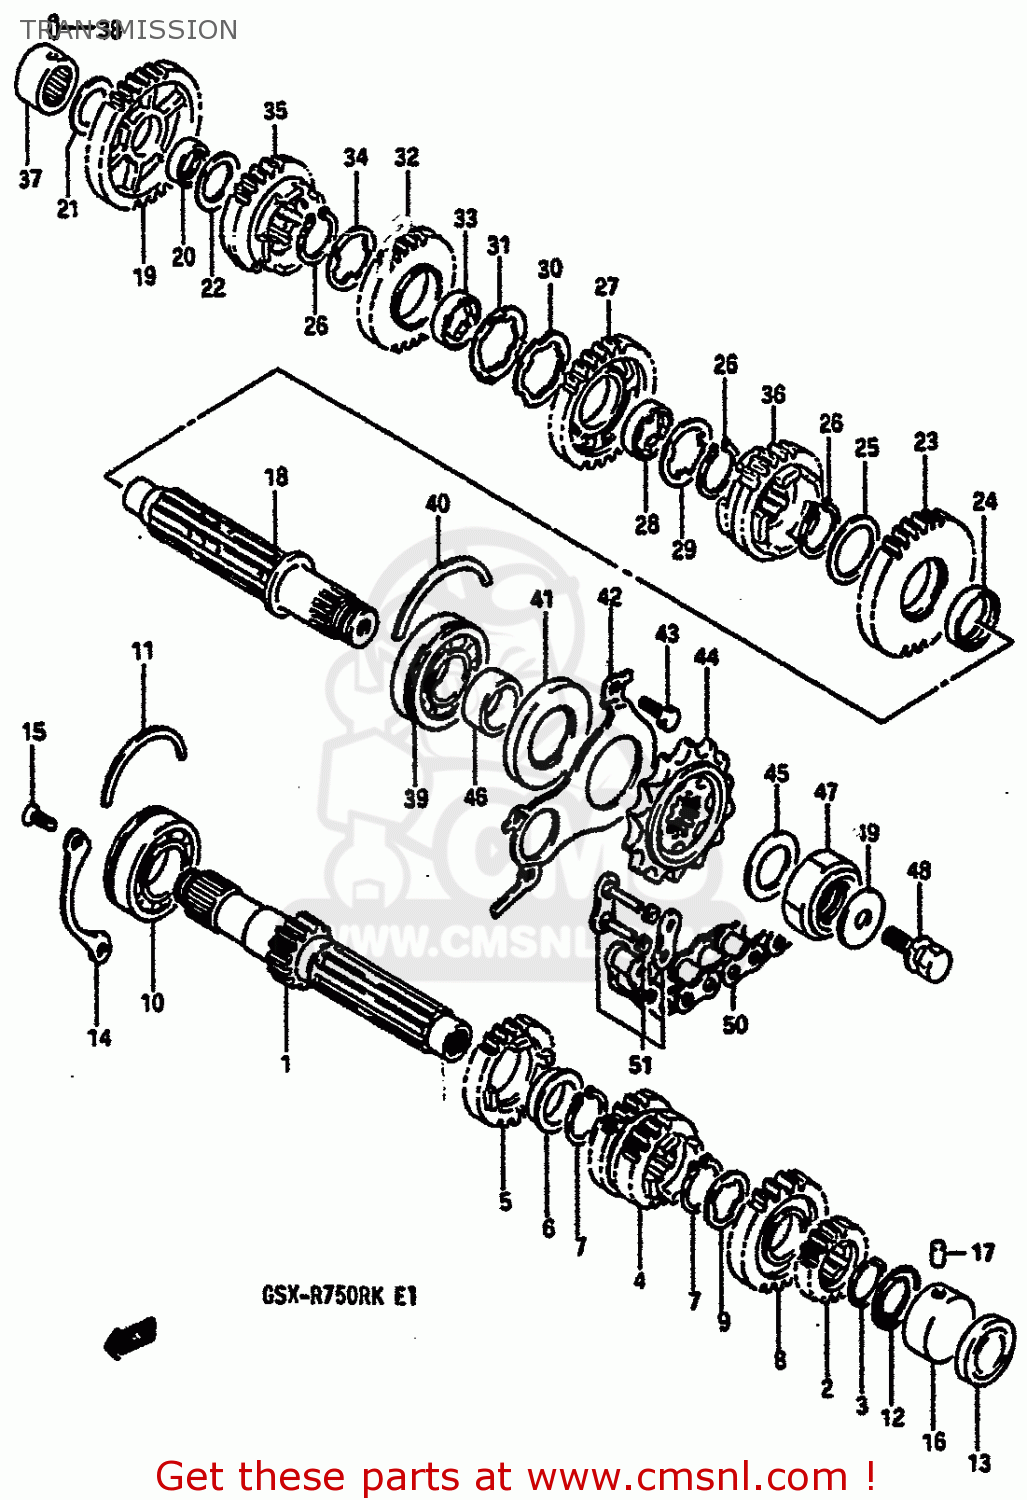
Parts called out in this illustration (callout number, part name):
1	COUNTERSHAFT (NT:13)
2	GEAR,2ND DRIVE (NT:17)
3	CIRCLIP
4	GEAR,3RD & 4TH DRIVE(NT:19/20)
5	GEAR,5TH DRIVE
6	BUSHING
7	RING,SNAP
8	GEAR,6TH DRIVE (NT:20)
9	WASHER,LOCK
10	BEARING(25X62X17)
11	C-RING
12	SEAL,OIL(20X31.2X2.7)
13	CAP,COUNTER SHAFT,L
14	RETAINER,CNTR SHAFT BEARING
15	SCREW
16	BEARING(20X34X17.5)
17	PIN
18	DRIVESHAFT
19	GEAR,1ST DRIVEN (NT:31)
20	BUSH(22X26X9)
21	WASHER
22	WASHER
23	GEAR,2ND DRIVEN (NT:32)
24	BUSH(28X32X8)
25	WASHER, THRUST
26	CIRCLIP
27	GEAR,3RD DRIVE
28	BUSH
29	WASHER,LOCK
30	WASHER,LOCK
31	WASHER
32	GEAR,4TH DRIVE
33	BUSH
34	WASHER,LOCK
35	GEAR,5TH DRIVE
36	GEAR,6TH DRIVEN (NT:24)
37	BEARING(20X34X20)
38	PIN
39	BEARING(25X62X17)
40	C-RING
41	SEAL,OIL(34X62X6)
42	RETAINER,DRIVE SHAFT OIL SEAL
43	BOLT
44	SPROCKET,ENGINE (NT:15)
45	WASHER,THRUST
46	SPACER(25X34X17.5)
47	NUT
48	BOLT
49	WASHER
50	CHAIN,DRIVE (50GSVX104L)RK
51	JOINT
